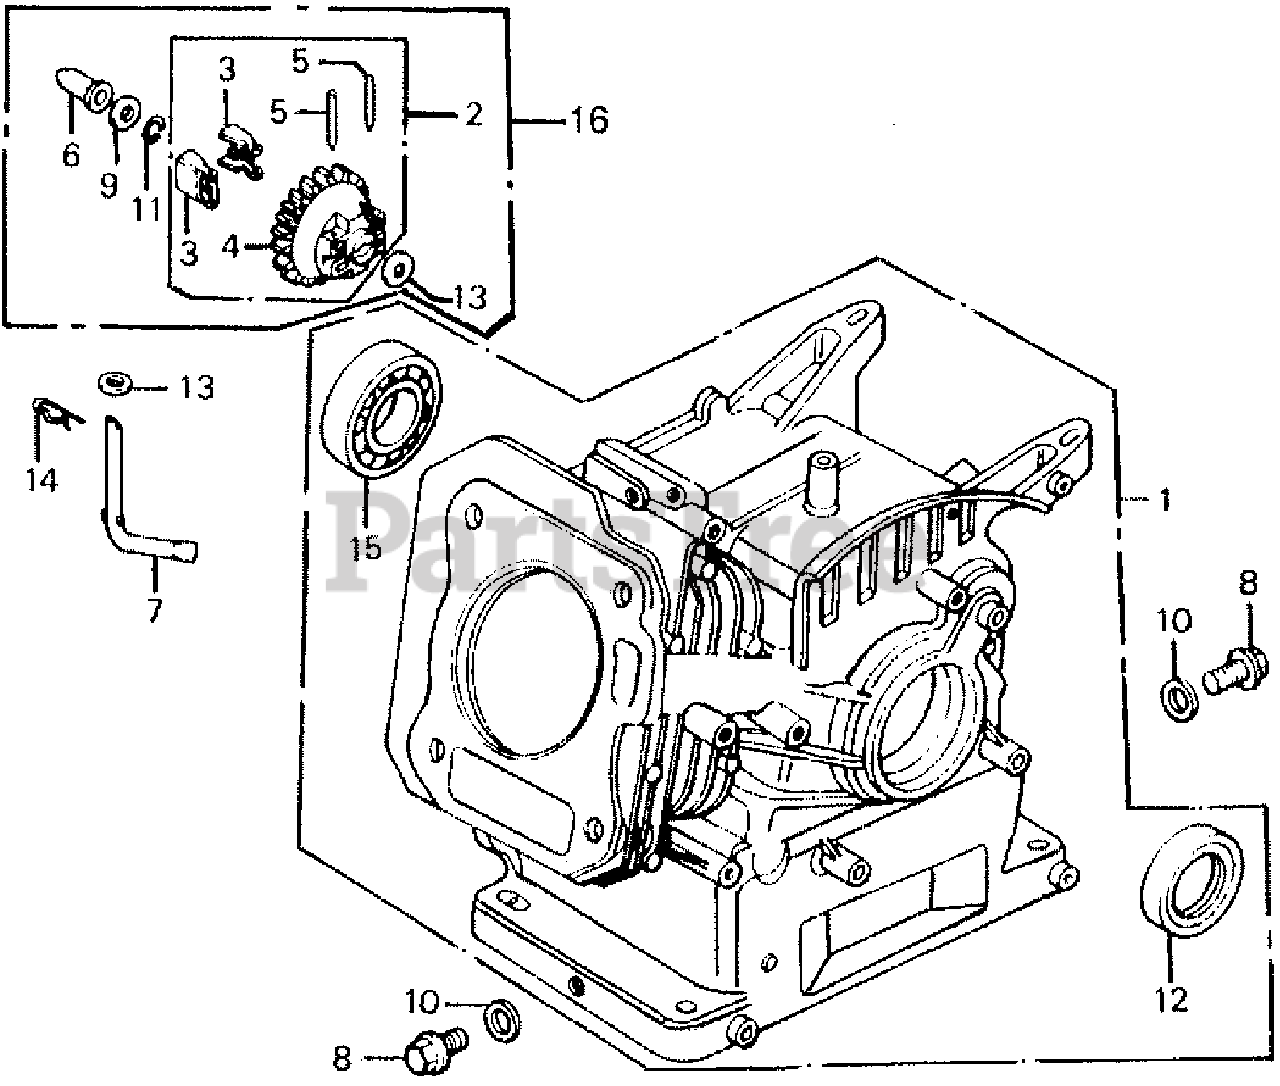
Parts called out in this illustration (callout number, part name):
1	CYLINDER ASSY.
2	GOVERNOR ASSY.
3	WEIGHT, GOVERNOR
4	HOLDER, GOVERNOR WEIGHT
5	PIN, GOVERNOR WEIGHT
6	SLIDER, GOVERNOR
7	SHAFT, GOVERNOR ARM
8	BOLT, DRAIN PLUG
9	WASHER, THRUST (6MM)
10	WASHER, DRAIN PLUG (10.2MM)
11	CLIP, GOVERNOR HOLDER
12	OIL SEAL (25X41X6)
13	WASHER, PLAIN (6MM)
14	PIN, LOCK (8MM)
15	BEARING, RADIAL BALL (6205)
16	GOVERNOR KIT
